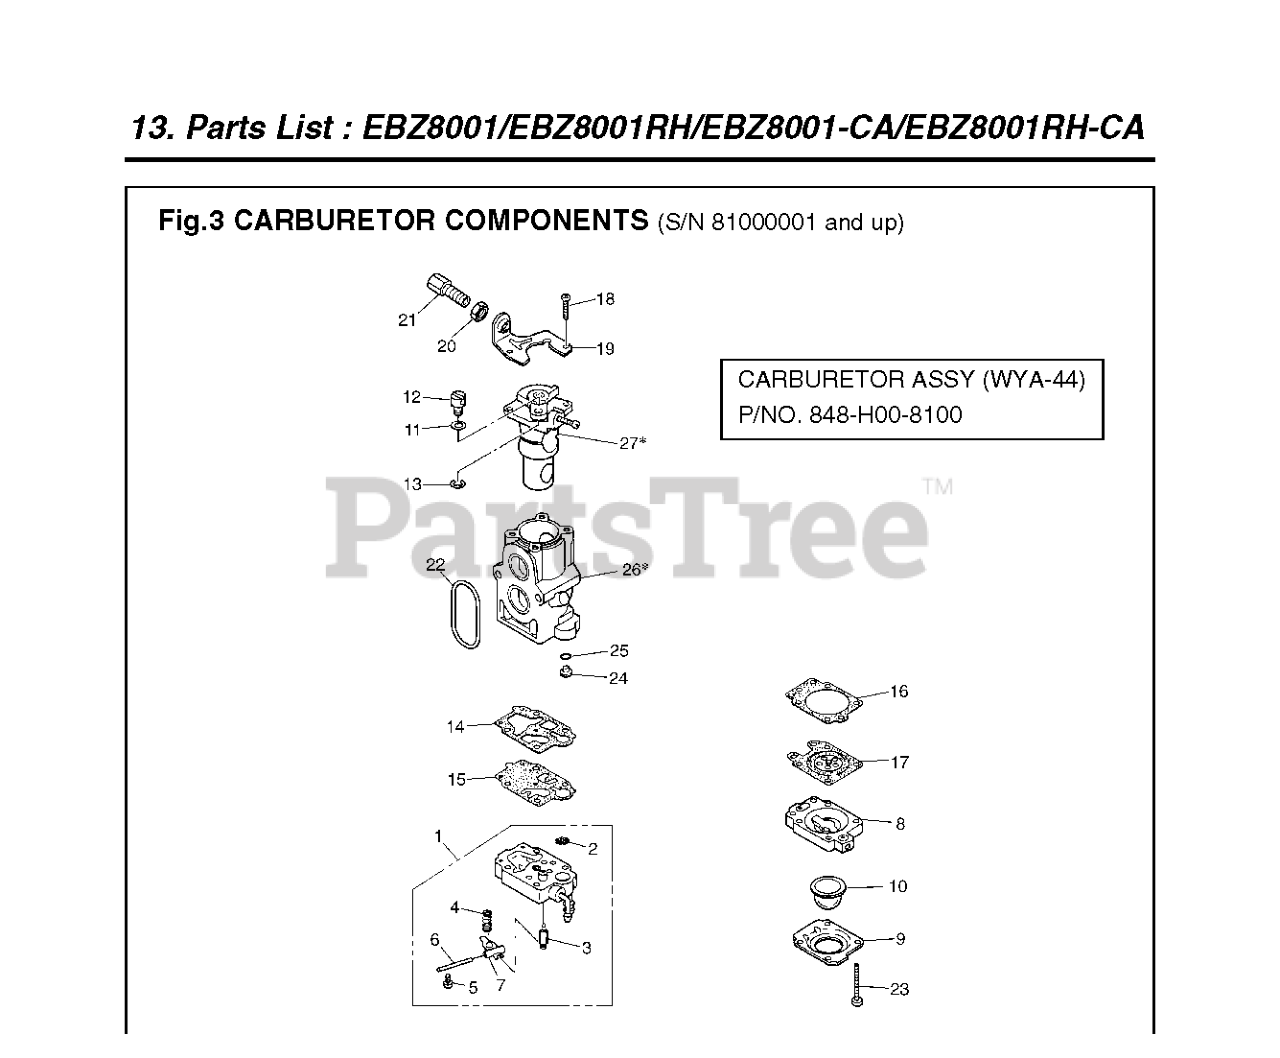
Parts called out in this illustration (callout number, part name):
1	BODY-A-PUMP
9	1OVER
11	WASHER
12	SWIVEL
13	RING
15	DIAPHRAGM
18	SCREW
19	BRACKET
20	NUT
21	ADJUSTER
22	RING
26	CARBURETOR-A
27	CARBURETOR-A
